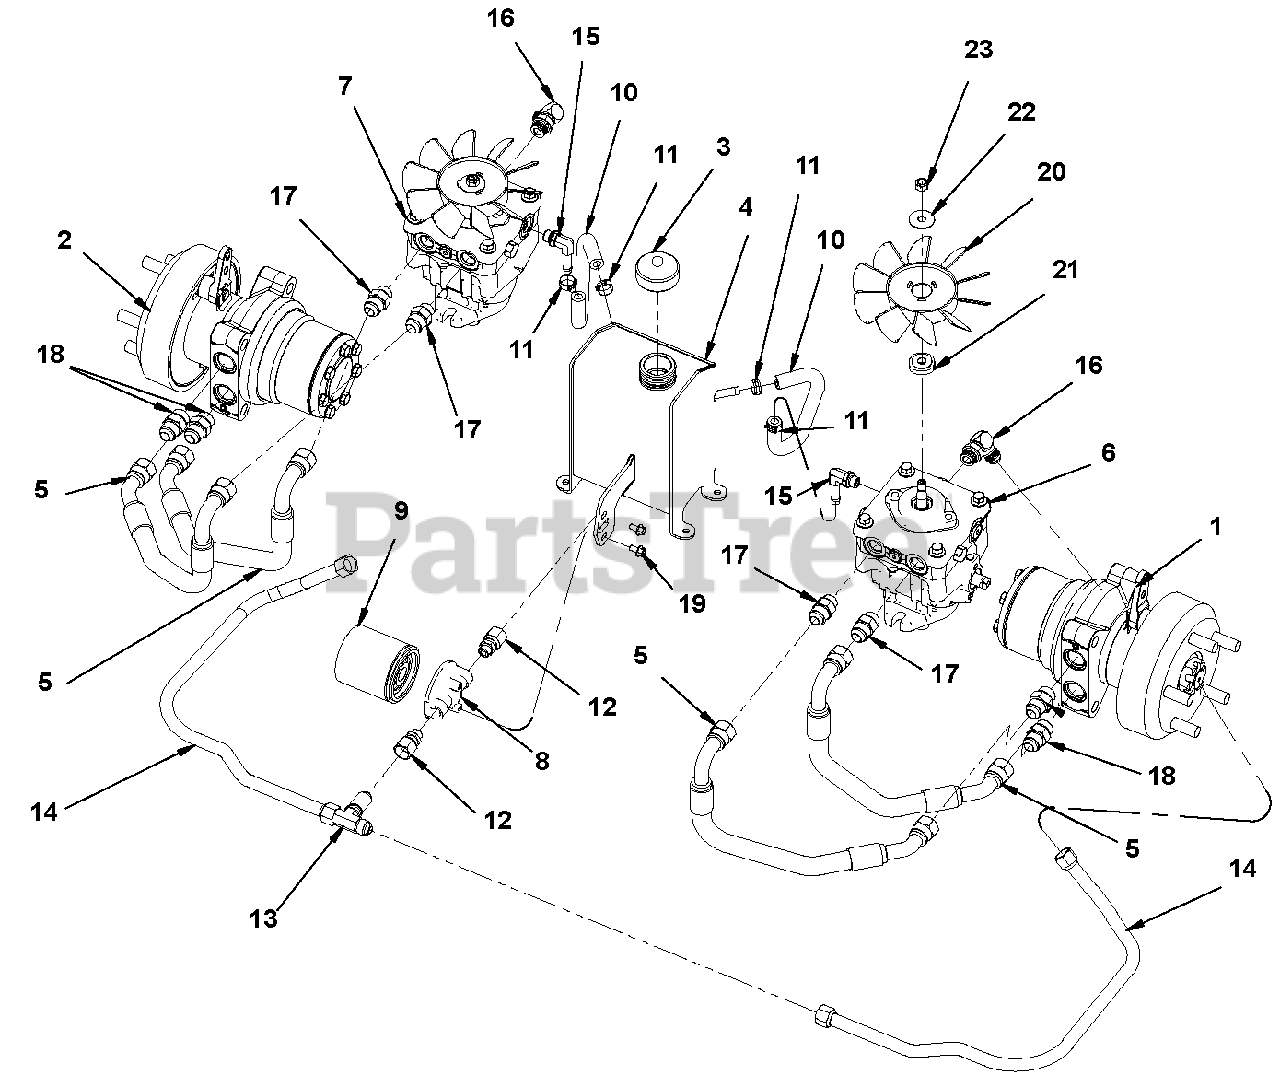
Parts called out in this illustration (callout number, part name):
1	Motor Assembly, LH Wheel Hydro-Gear ***
2	Motor Assembly, RH Wheel Hydro-Gear***
3	Cap, Oil Reservoir Breather
4	Weldment, Oil Tank
5	Hose, Hydraulic 5/8 X 18.75
6	Pump, LH BDP16A *
7	Pump, RH BDP16A *
8	Head, Filter
9	Filter, 25 MICRON
10	Hose, Hydraulic 3/8 X 12.5 Long
11	Clamp, .690 OD Hose PINCH
12	Fitting, #6 Male OR x #8 Female 37° JIC
13	Fitting, Bulk Head #8 JIC Tee
14	Hose, #8 TOC W/ # 8 SWL 37°JIC
15	Fitting, 9/16 MOR X 3/8 Hose 90º
16	Fitting, HYD Elbow 3/4 O-RING, 3/4JIC
17	Adapter, 3/4-16MORX7/8-14 JIC
18	Adapter, 7/8-14MORX 7/8-14JIC
19	Bolt, 1/4-20 X .500 WSH 5
20	Fan, BDP16 Plastic Cooler
21	Hub, BDP16 Fan
22	Washer, .375 x 1.25 x .072 Bellville
23	Locknut, .38-24 Crown
181903	Lever, Brake (Hydro-Gear)
